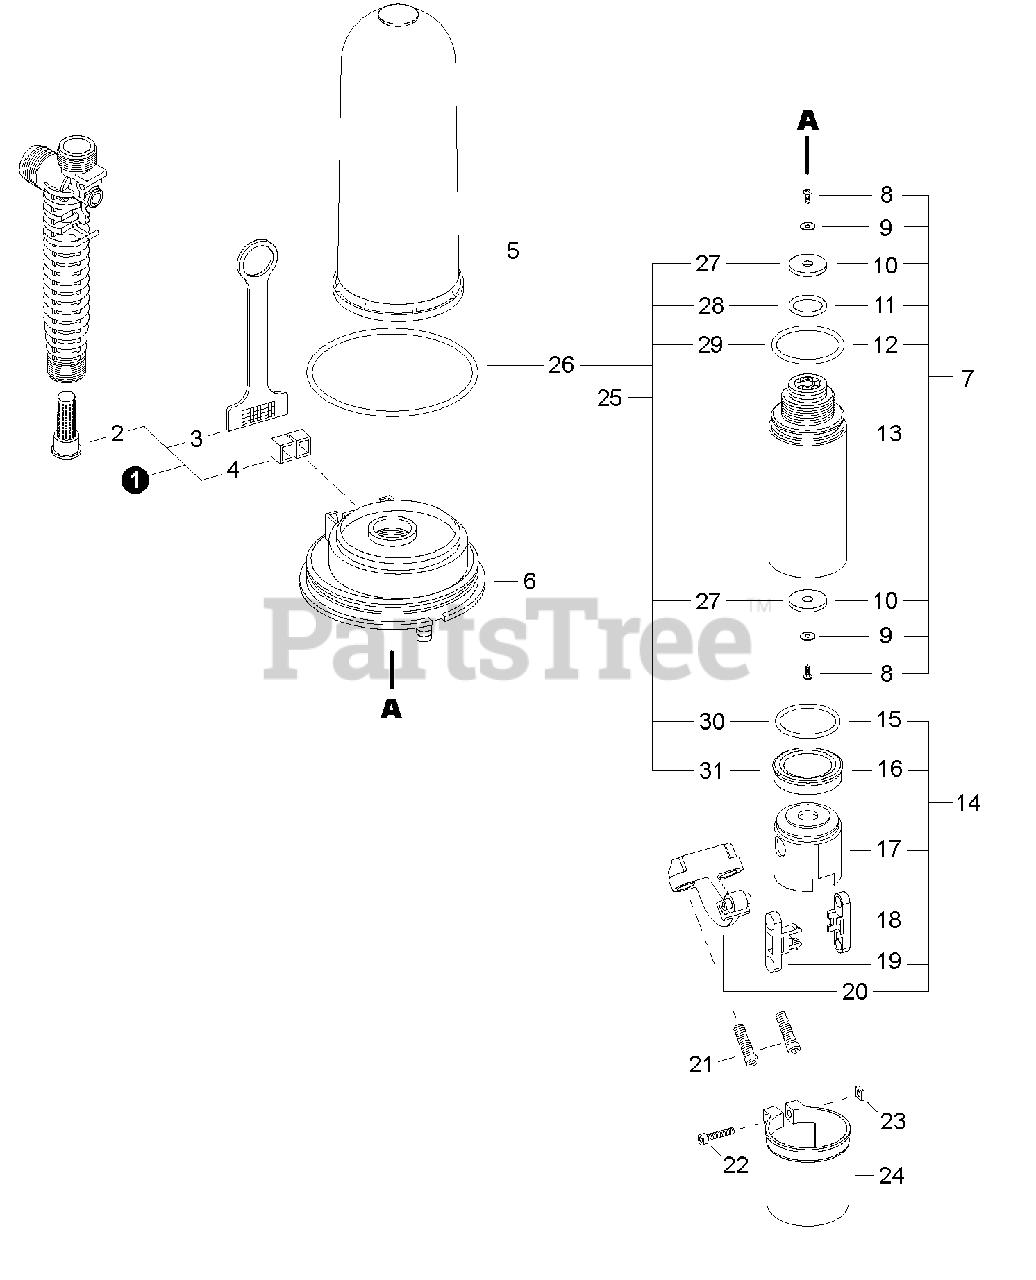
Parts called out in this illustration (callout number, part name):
1	FILTER KIT
2	FILTER, SPRAY GUN
3	FILTER, IN-TANK
4	FILTER, CARTRIDGE
5	CHAMBER, PRESSURE
6	BASE, PRESSURE CHAMBER
7	CYLINDER/PISTON ASSY
8	SCREW, CYLINDER
9	WASHER
10	SEAL, VALVE
11	O-RING, CYLINDER - SMALL
12	O-RING, CYLINDER - LARGE
13	CYLINDER
14	PISTON ASSY
15	SPRING, SEAL
16	SEAL, PISTON
17	PISTON
18	ROD, CONNECTING - A
19	ROD, CONNECTING - B
20	LEVER, PIVOT
21	SCREW, LEVER
24	CAP, DUST
25	REPAIR KIT, PUMP
26	O-RING, PRESSURE CHAMBER
27	SEAL, VALVE
28	O-RING, CYLINDER - SMALL
29	O-RING, CYLINDER - LARGE
30	SPRING, SEAL
31	SEAL, PISTON
